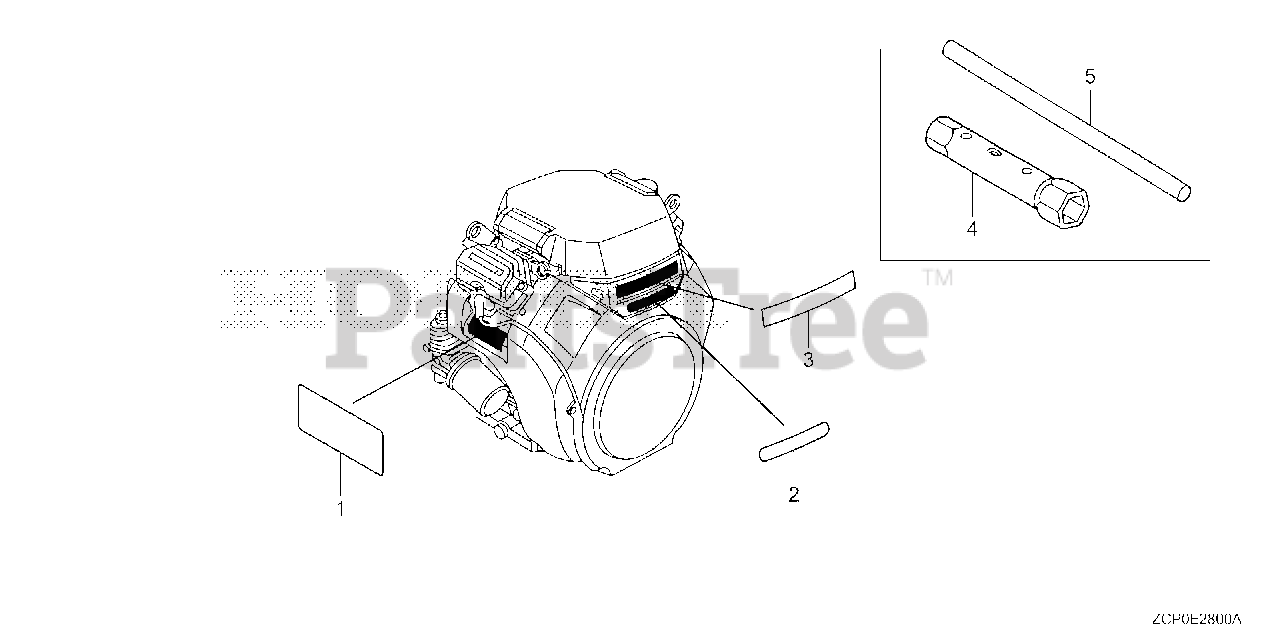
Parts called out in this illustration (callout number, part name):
1	MARK, OPERATOR CAUTION (PICTOGRAPH)
2	EMBLEM (GX690)
3	MARK, HONDA
